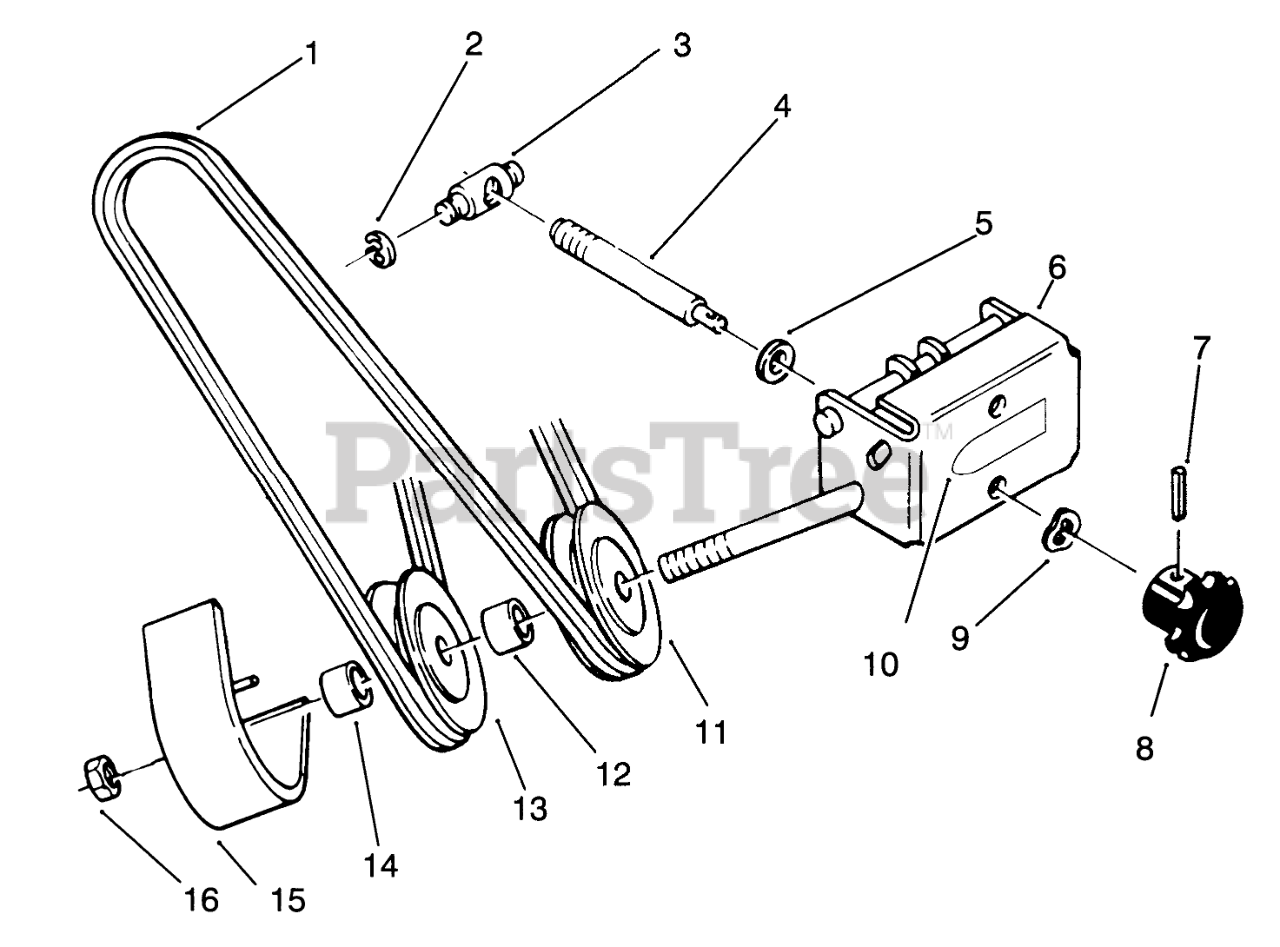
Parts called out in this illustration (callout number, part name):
1	V-BELT
2	RING-RETAINING
3	TRUNNION-DOUBLE
4	ROD ADJ
5	WASHER-FLAT
6	Front Support
7	PIN-ROLL
8	KNOB-ADJUSTMENT
9	WASHER-SPRING
10	DECAL-ATTACH A-MATIC
11	Pulley-V
12	SPACER
13	PULLEY-FLAT IDLER
14	SPACER-OUTER
15	Belt Cover
16	Nut
